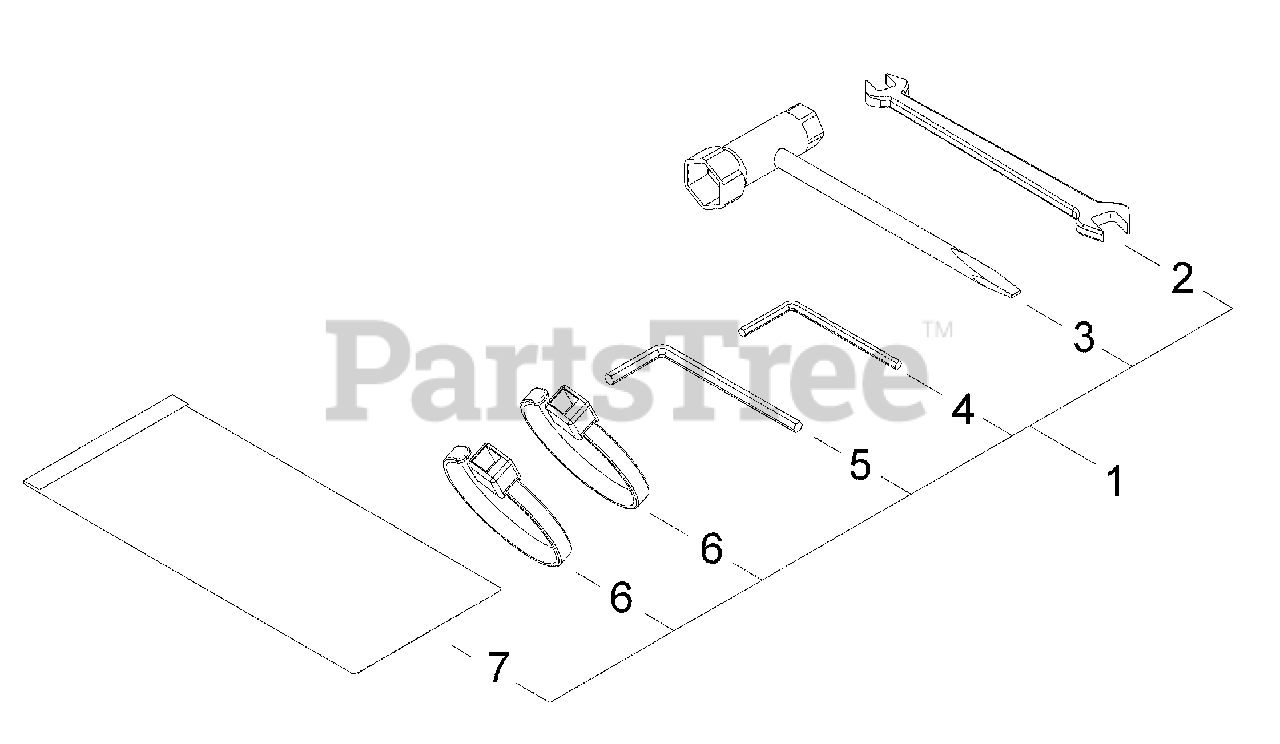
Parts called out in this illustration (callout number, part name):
1	TOOL KIT
2	SPANNER - 8X10mm
3	T-WRENCH - 13X16mm
4	HEX KEY - 4mm
5	HEX KEY - 6mm
6	BAND
7	BAG, TOOL
